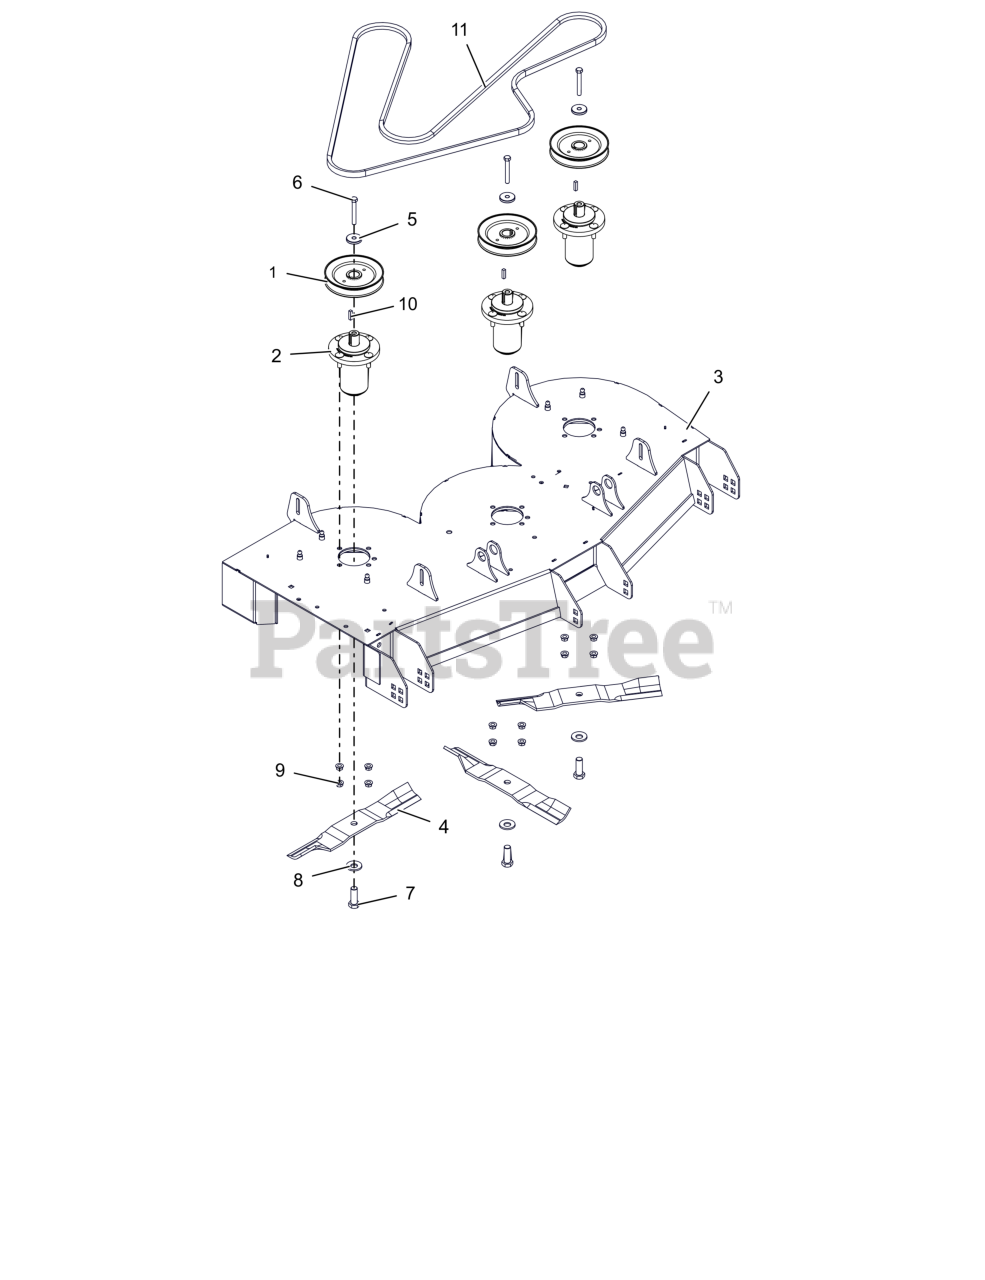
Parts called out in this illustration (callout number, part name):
1	PULLEY- V-1.000 ID X 5.750 OD
2	ASM, MAINT FREE ALUM SPINDLE
3	WLDMT, DECK RIDGELINE 48 (ORANGE)
4	BLADE, 16.19" MOWER (HI-LIFT)
5	RETAINER, SHEAVE
6	BLT, HEX .38-16X2.75 G8 ZCC
7	BLT, HEX .62-18X1.75 G8 ZCC
8	WSHR-BLVL .669X1.535X.138
9	NUT-LK-CTR-FLG .375-16 GF ZCC
10	KEY, SQ .25X.25X1.00 RC 40-50
11	V-BELT, HB SECTION 123.230
